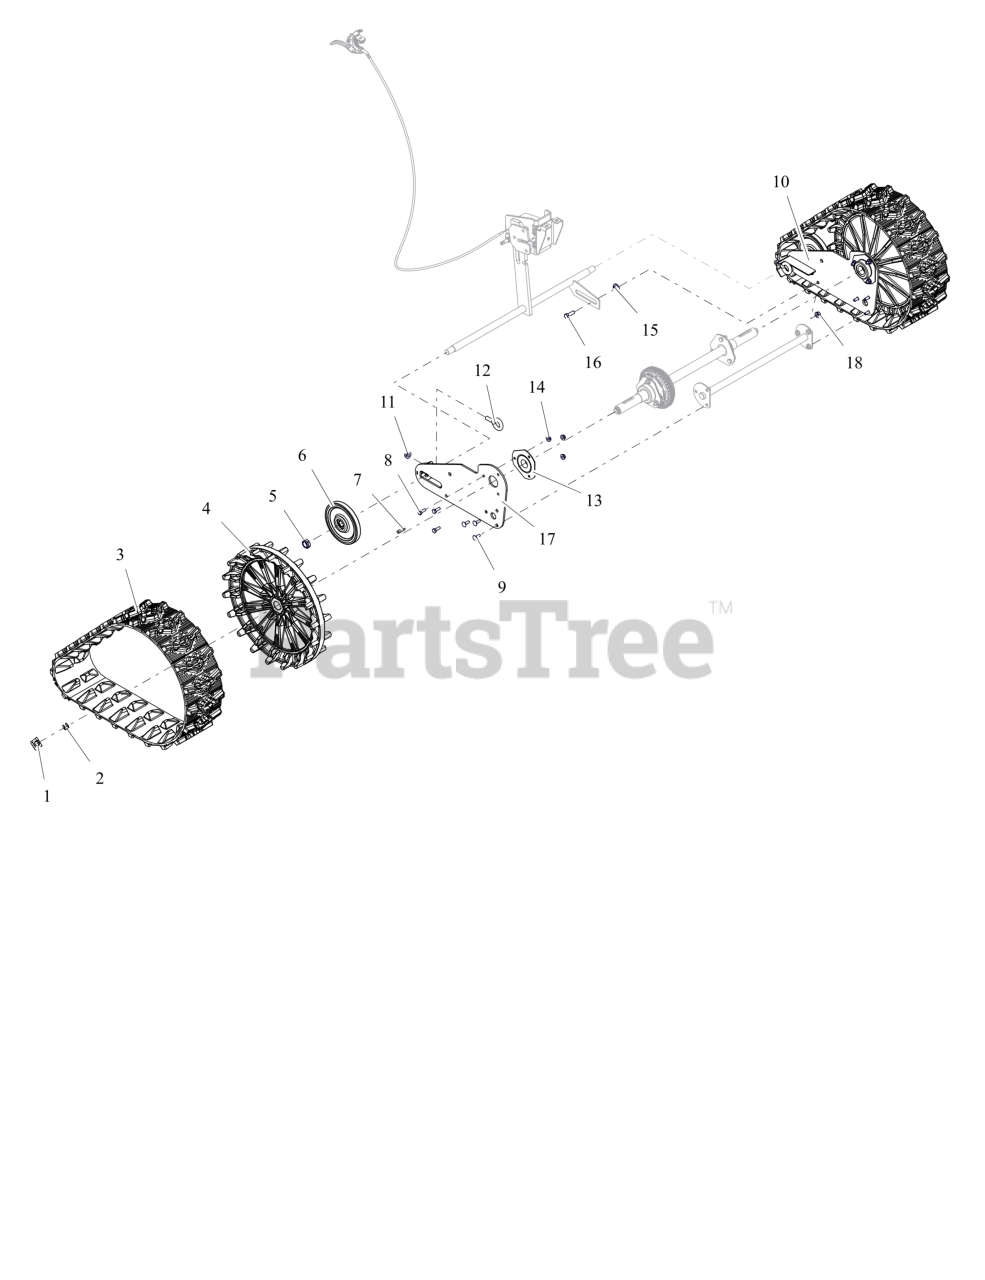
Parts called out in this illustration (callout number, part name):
1	CLIP, SNAP .625 DIA
2	RG-RTNG-EXT .625X.042
3	TRACK, RUBBER - 22 PITCHES
4	SPROCKET, LARGE TRACK DRIVE
5	NUT, NYL LK .625-18 ZCC
6	WHEEL, BOGIE - SINGLE BEARING
7	KEY-RECT .25X.188X1.00
8	BLT, HEX .25-20X.75 G5 ZCC
9	BLT, RHSN .25-20X.750 G5 ZCC
10	PLATE, SIDE-BWT LH WLDMT
11	NUT-LK-CTR-FLG .375-16 GF ZCC
12	BLT-EYE .375-16X.880 YWZC
13	BRG-FLG 1.003/1.000 3 BOLT
14	NUT-LK-TOP-FLG .250-20 GF ZCC
15	BSHG-FLG .325X.499X.3X.875
16	BLT,HEX .31-18X1.00 G5 ZCC
17	PLATE, SIDE-BWT RH WLDMT
18	NUT-LK-TOP-FLG .312-18 GF ZCC
